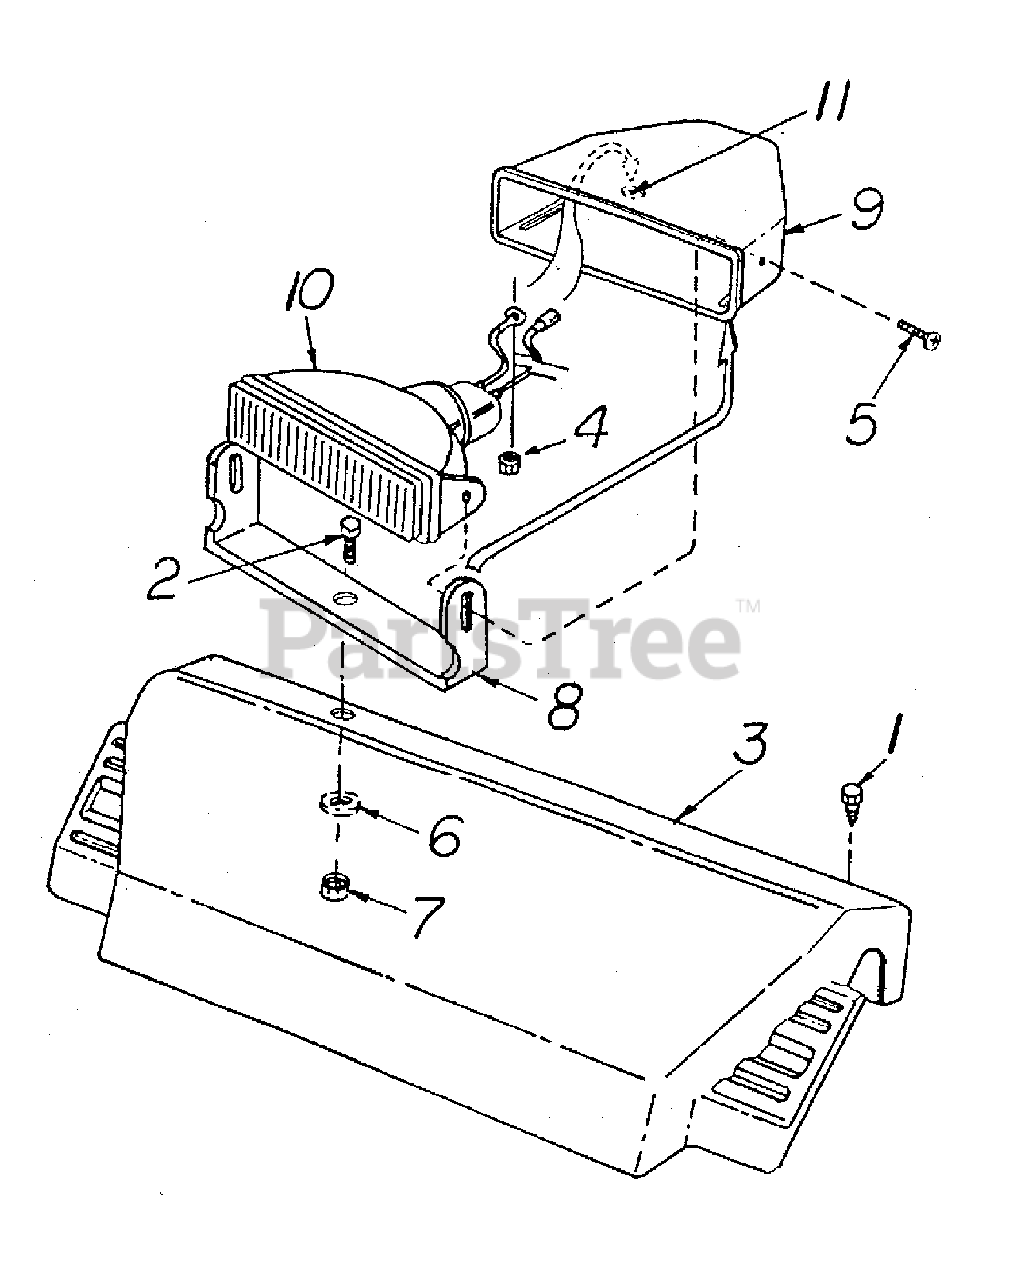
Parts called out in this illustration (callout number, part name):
1	Pan Head B-Tapp Screw #10
2	Carriage Bolt 5/16-18 x .75
3	Handle Panel
4	Hex Sems Nut 1/4-20
5	Phillips Pan Head Screw M 4 x 16
6	Fl-Wash .344 ID x .88 OD
7	Hex Ins L-Nut 5/16-18
8	Lamp Mounting Bracket
9	Halogen Lamp Housing
10	Lamp/Lens Housing Ass'y
11	Grommet .38 ID x .50 OD x 12
